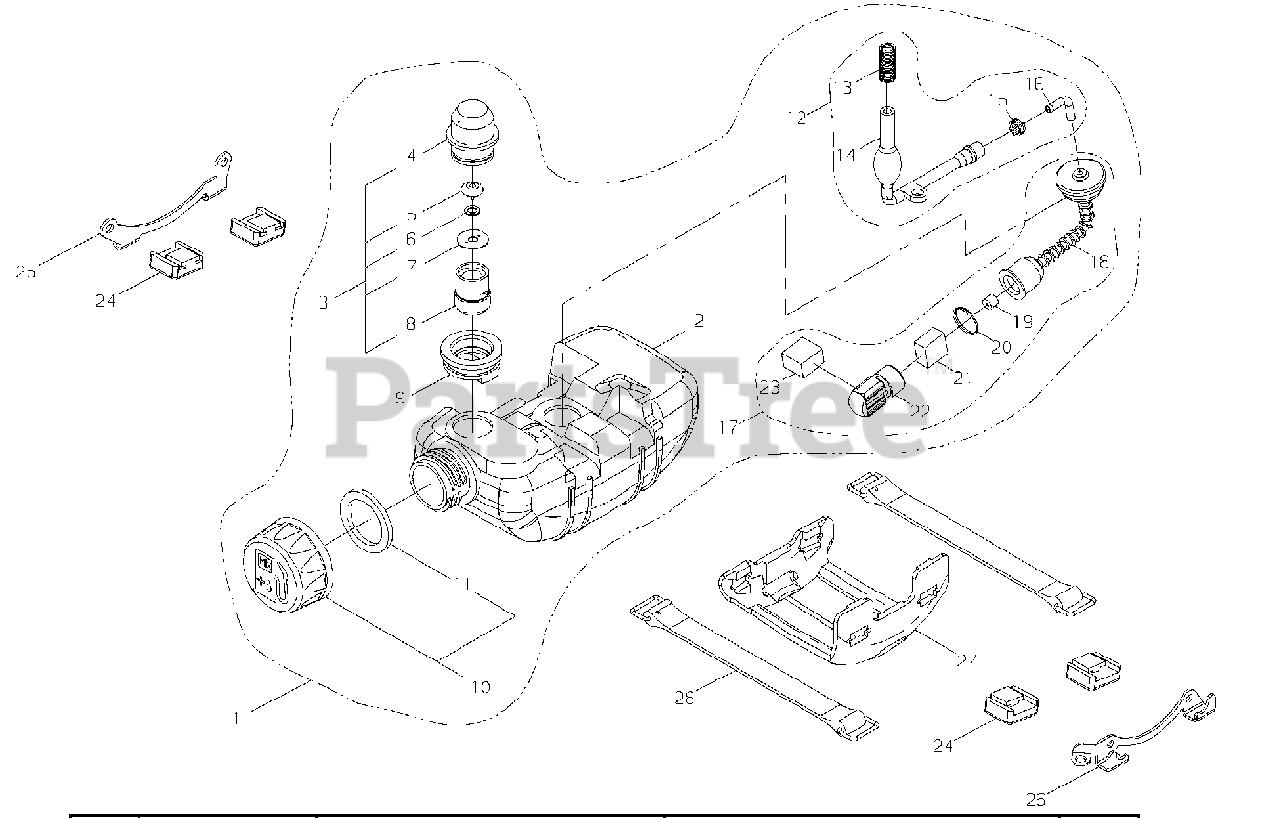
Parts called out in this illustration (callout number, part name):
1	FUEL TANK ASSY
2	TANK, FUEL
3	VENT, FUEL TANK
4	CAP, BREATHER
5	VALVE, BREATHER
6	WASHER
7	RETAINER
8	HOLDER, VENT
9	GROMMET
10	CAP ASSY
11	GASKET, CAP
12	FUEL PIPE ASSY
13	CLIP
14	CONNECTOR, PIPE
15	RING, RETAINING
16	CONNECTOR, PIPE
17	FUEL FILTER ASSY
18	PICK-UP TUBE
19	VENT, FUEL TANK
20	CLIP
21	FILTER, FUEL - B
22	WEIGHT, FUEL FILTER
23	FILTER, FUEL - A
24	CUSHION
25	BRACKET - INNER
26	BRACKET - OUTER
27	GUARD, FUEL TANK
28	STRAP
